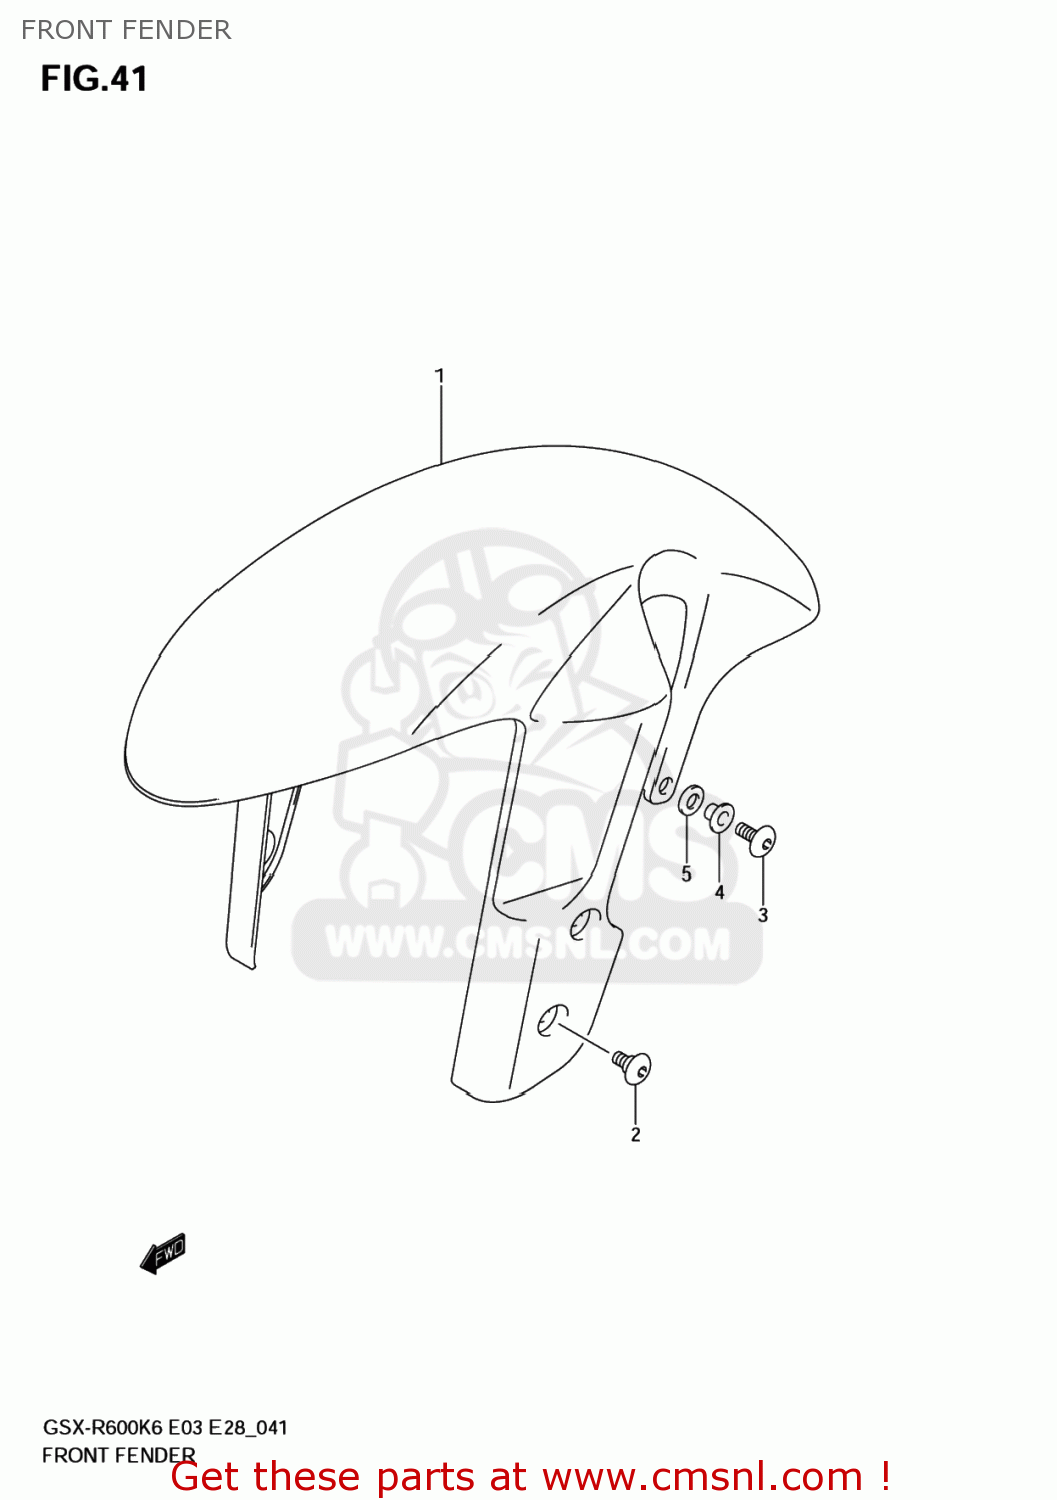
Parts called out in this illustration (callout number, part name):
1	FENDER,FR
2	SCREW(6X12)
3	SCREW(6X16)
4	WASHER
5	WASHER,FR FENDER FR NO.2
